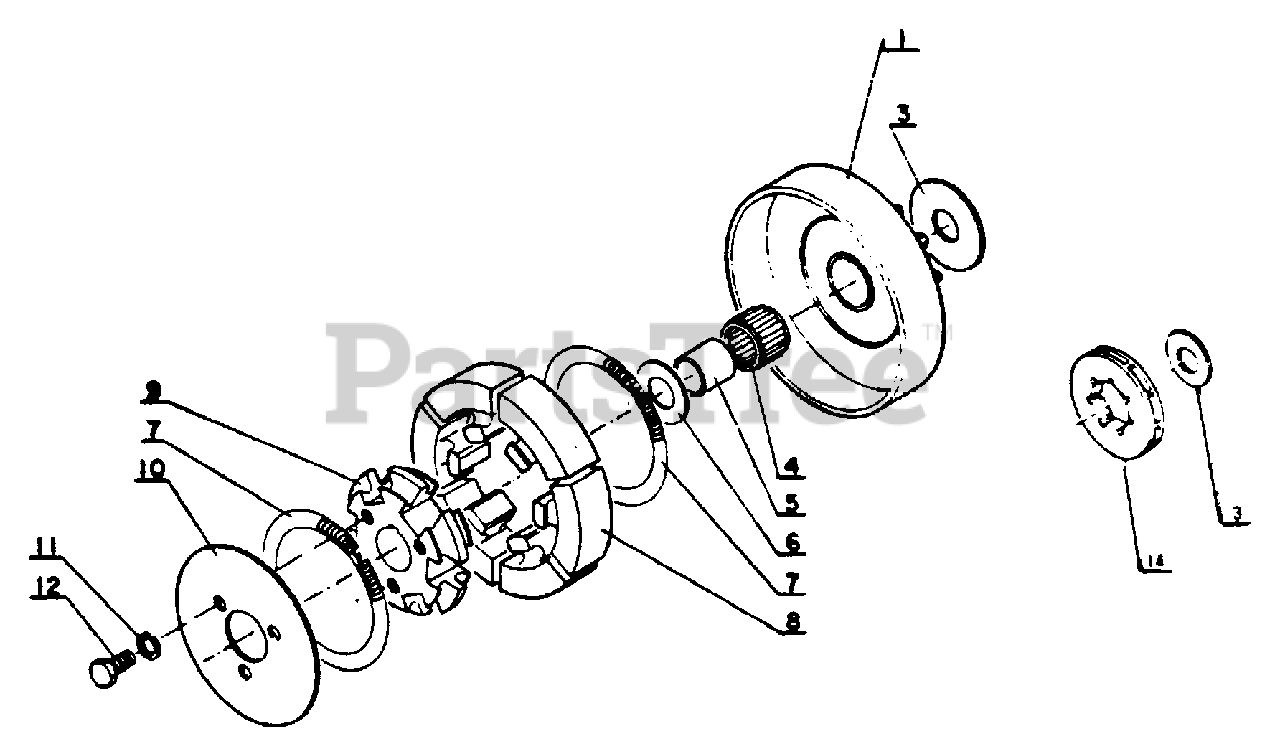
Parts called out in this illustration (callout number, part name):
1	DRUM, CLUTCH
3	WASHER, CLUTCH
4	BEARING, NEEDLE
5	SPACER
6	WASHER, CLUTCH
7	SPRING, CLUTCH
8	SHOE, CLUTCH
9	HUB, CLUTCH
10	PLATE, CLUTCH
11	WASHER - SPRING
12	BOLT
14	SPROCKET, RIM
